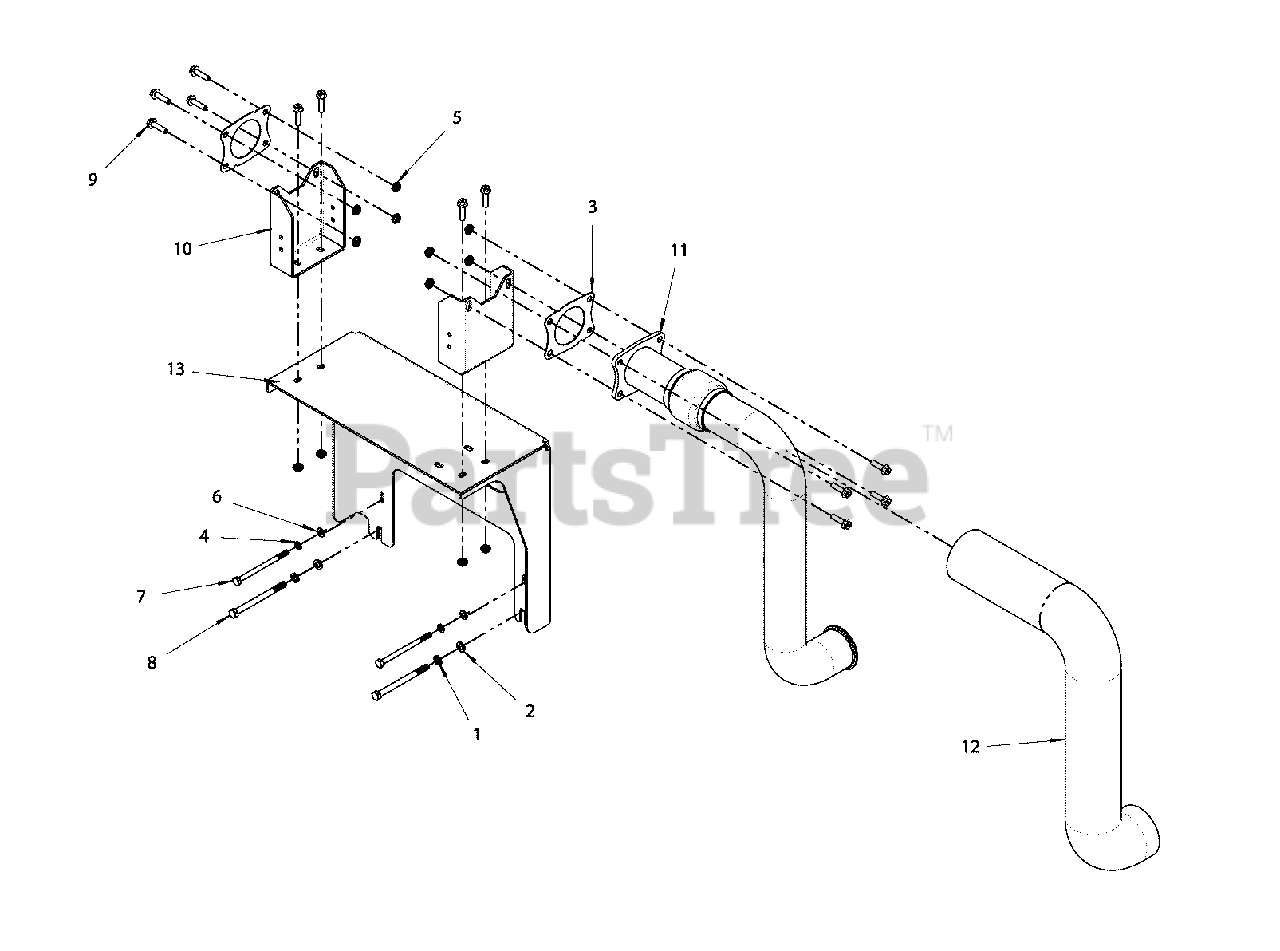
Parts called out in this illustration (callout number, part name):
1	* WASHER
2	* WASHER
3	GASKET
4	* WASHER
5	* NUT
6	* WASHER
7	* BOLT
8	* BOLT
9	* BOLT
10	* SUPPORT
11	TUBE
12	SLEEVE
13	* BRACKET
